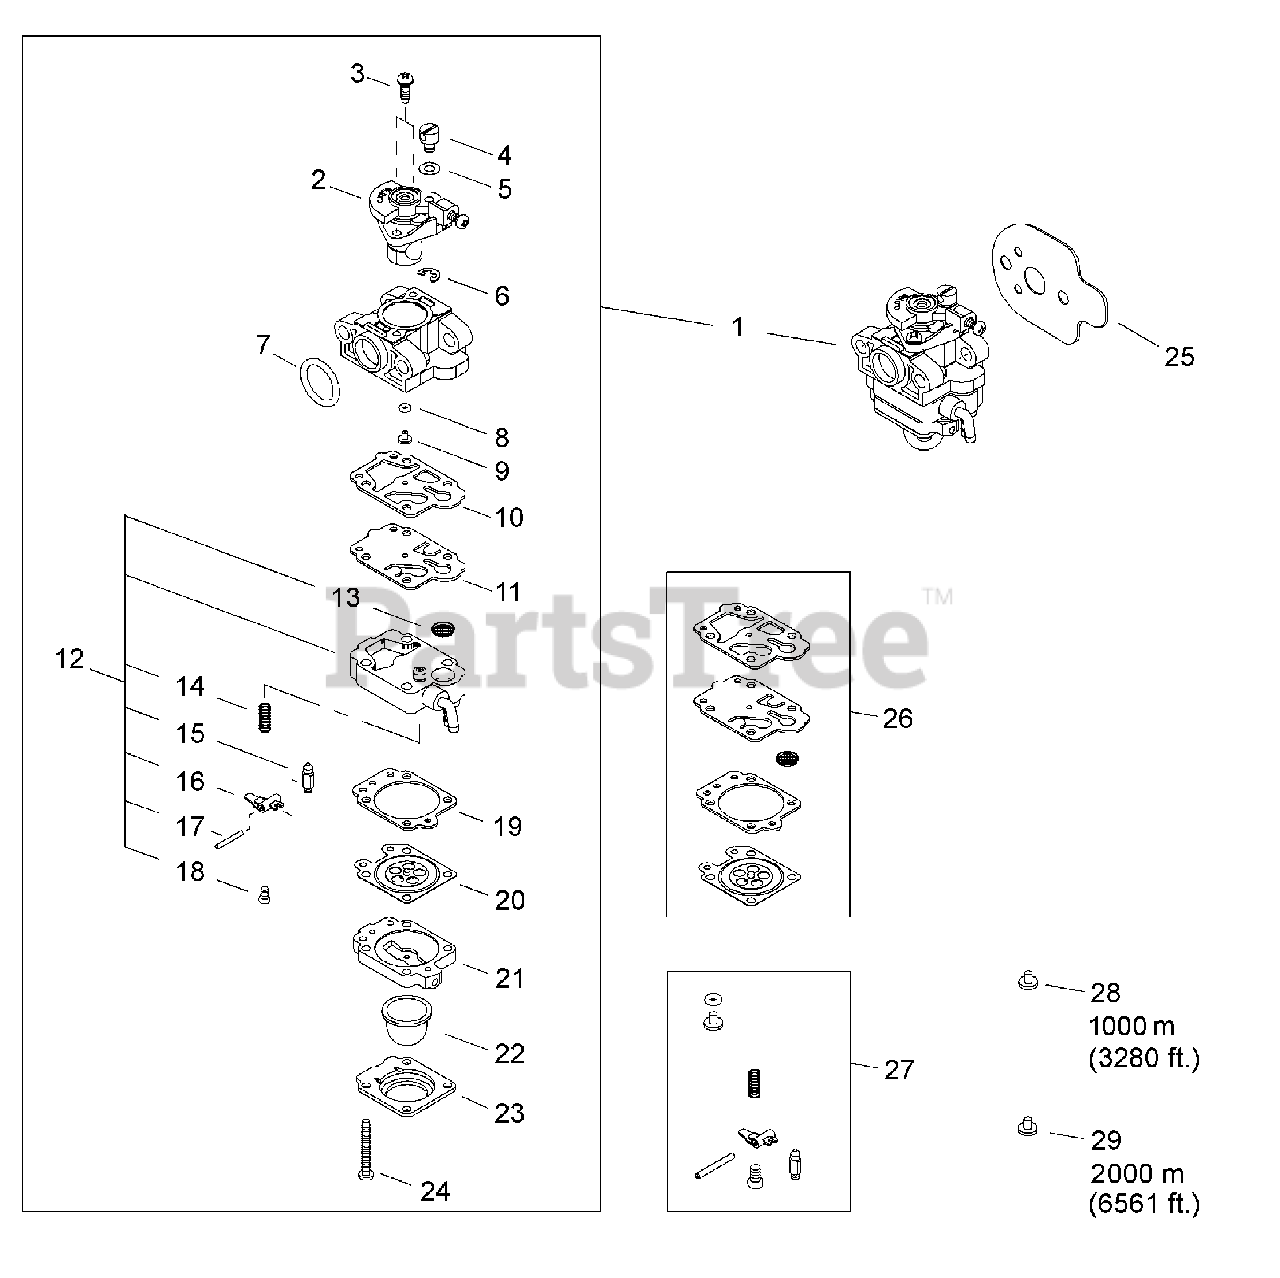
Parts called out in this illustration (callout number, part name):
1	CARBURETOR
2	VALVE ASSY, THROTTLE
3	SCREW, THROTTLE COLLAR
4	SWIVEL
5	WASHER
6	E-RING
7	O-RING 15
8	O-RING
9	JET, MAIN
10	GASKET, PUMP
11	DIAPHRAGM, PUMP
12	BODY ASSY, PUMP
13	SCREEN, FUEL INLET
14	SPRING, METERING LEVER
15	VALVE, INLET NEEDLE
16	LEVER, METERING
17	PIN, METERING LEVER
18	SCREW
19	GASKET, METERING DIAPHRAGM
20	DIAPHRAGM, METERING
21	BODY ASSY, PURGE
22	BULB, PURGE
23	RETAINER, PURGE BULB
24	SCREW
25	GASKET, INTAKE
26	GASKET / DIAPHRAGM KIT
27	VALVE KIT, INLET NEEDLE
28	JET, MAIN #40
29	JET, MAIN #39
